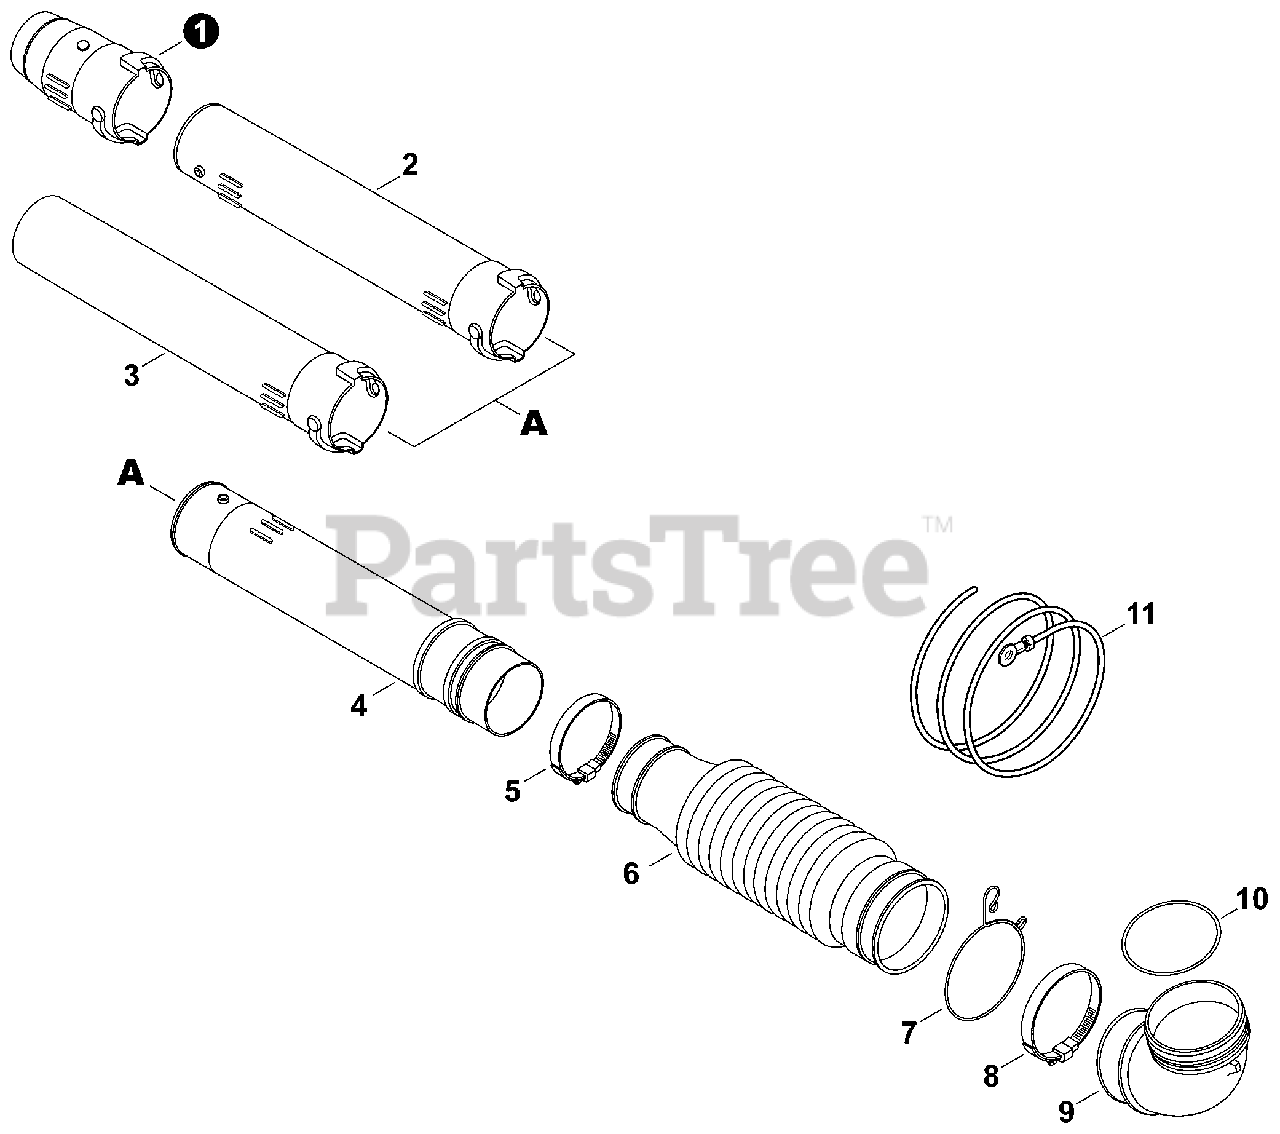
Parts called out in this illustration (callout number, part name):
1	TUBE, BLOWER - NOZZLE
2	TUBE, BLOWER - STRAIGHT
3	TUBE, BLOWER - NOZZLE
4	TUBE, BLOWER - SWIVEL
6	TUBE, BLOWER - FLEXIBLE
7	HOLDER, THROTTLE CABLE
9	TUBE, BLOWER - ELBOW
11	WIRE, STATIC DISCHARGE
